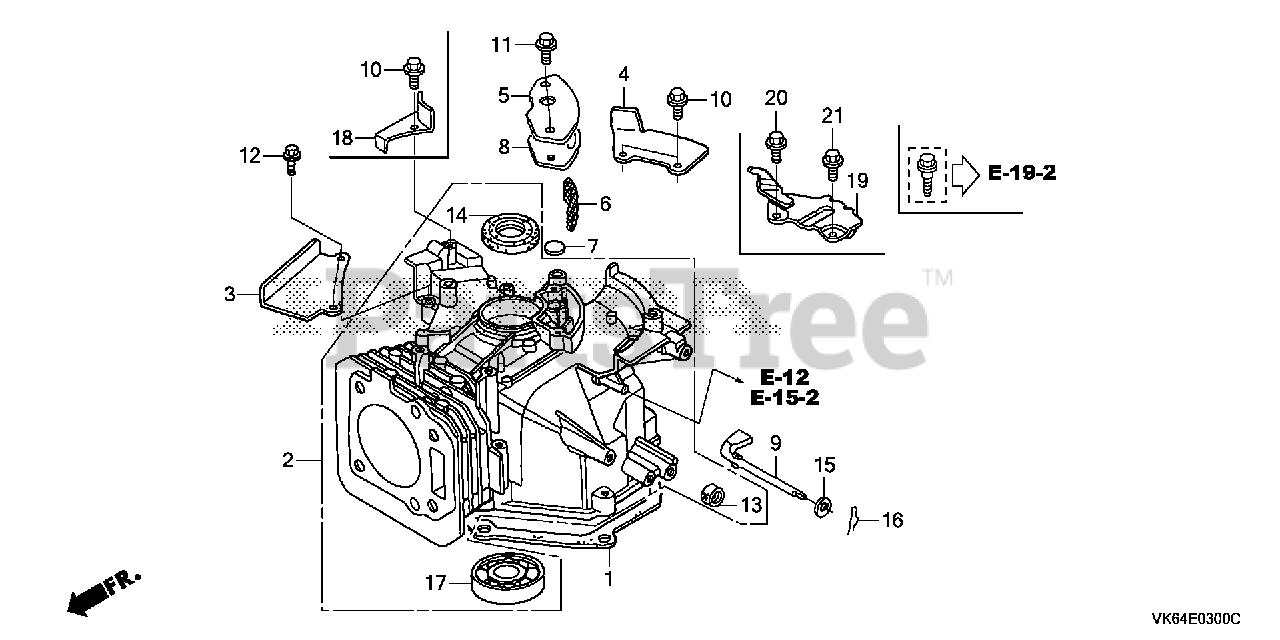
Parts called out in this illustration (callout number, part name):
1	GASKET, OIL PAN
1	GASKET, OIL PAN (NINGBO SIL GASKET)
2	CYLINDER ASSY.
3	PLATE, GUIDE
5	COVER, BREATHER
6	FILTER, BREATHER
7	VALVE, BREATHER
8	GASKET, BREATHER COVER
9	SHAFT, GOVERNOR ARM
10	BOLT, FLANGE (6X12) (CT200)
11	BOLT, FLANGE (6X14) (CT200)
12	BOLT, FLANGE (6X20) (CT200)
13	OIL SEAL (6X11X4) (ARAI)
14	OIL SEAL (25X38X7) (ARAI)
15	WASHER, PLAIN (6MM)
16	PIN, LOCK (8MM)
17	BEARING, RADIAL BALL (6205)
18	PLATE A, GUIDE
19	STAY, TANK
20	BOLT, FLANGE (6X14) (CT200)
21	BOLT, FLANGE (6X14) (CT200)
